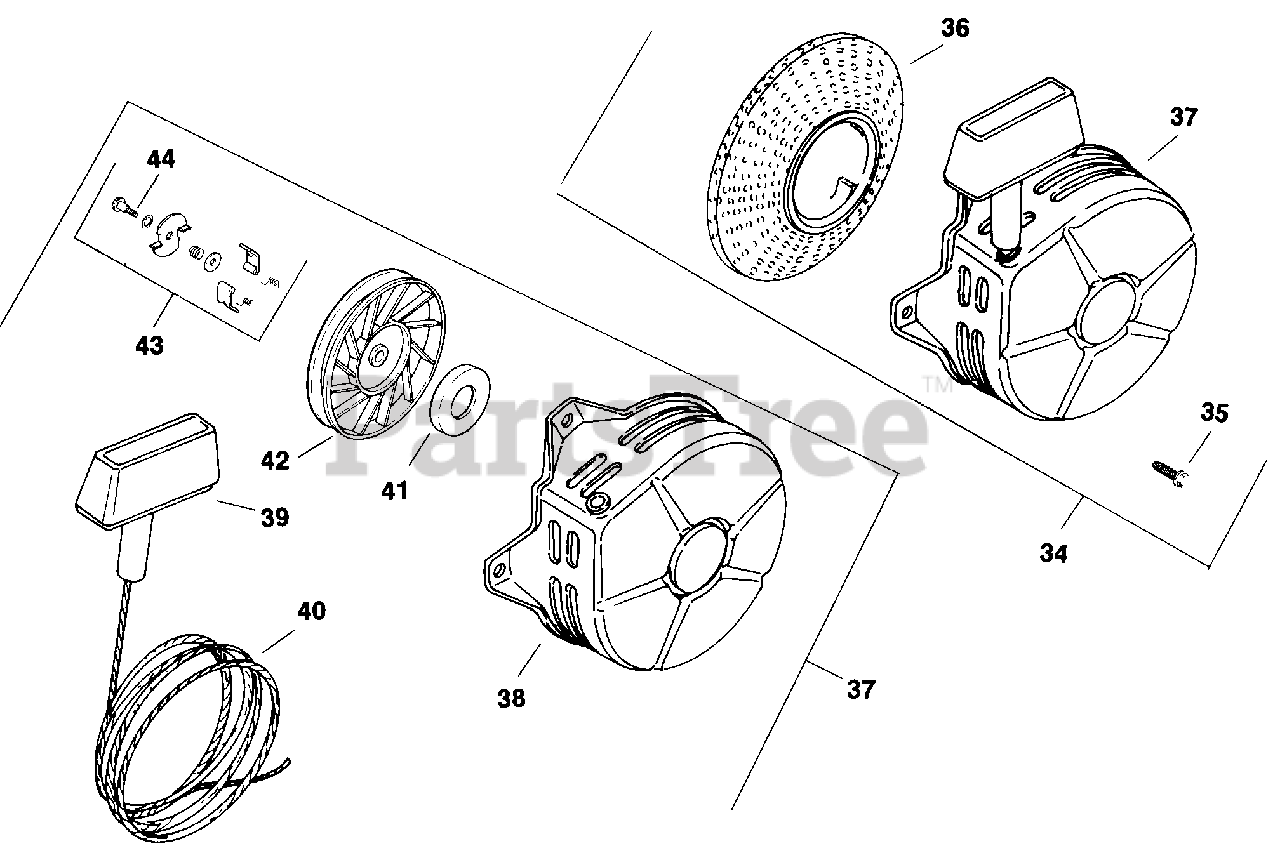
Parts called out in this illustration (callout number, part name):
34	KIT, STARTER W/CUP - DISCONTINUED
35	SCREW, FLG HD 10-24X1/4"
36	CUP W/SCREEN
37	STARTER, RECOIL - DISCONTINUED
39	HANDLE - USE 234452
40	ROPE - DISCONTINUED
41	SPRING & KEEPER - (#DSC)
42	PULLEY - (#DSC)
43	KIT, DOG REPAIR - (#DSC)
44	SCREW - DISCONTINUED
